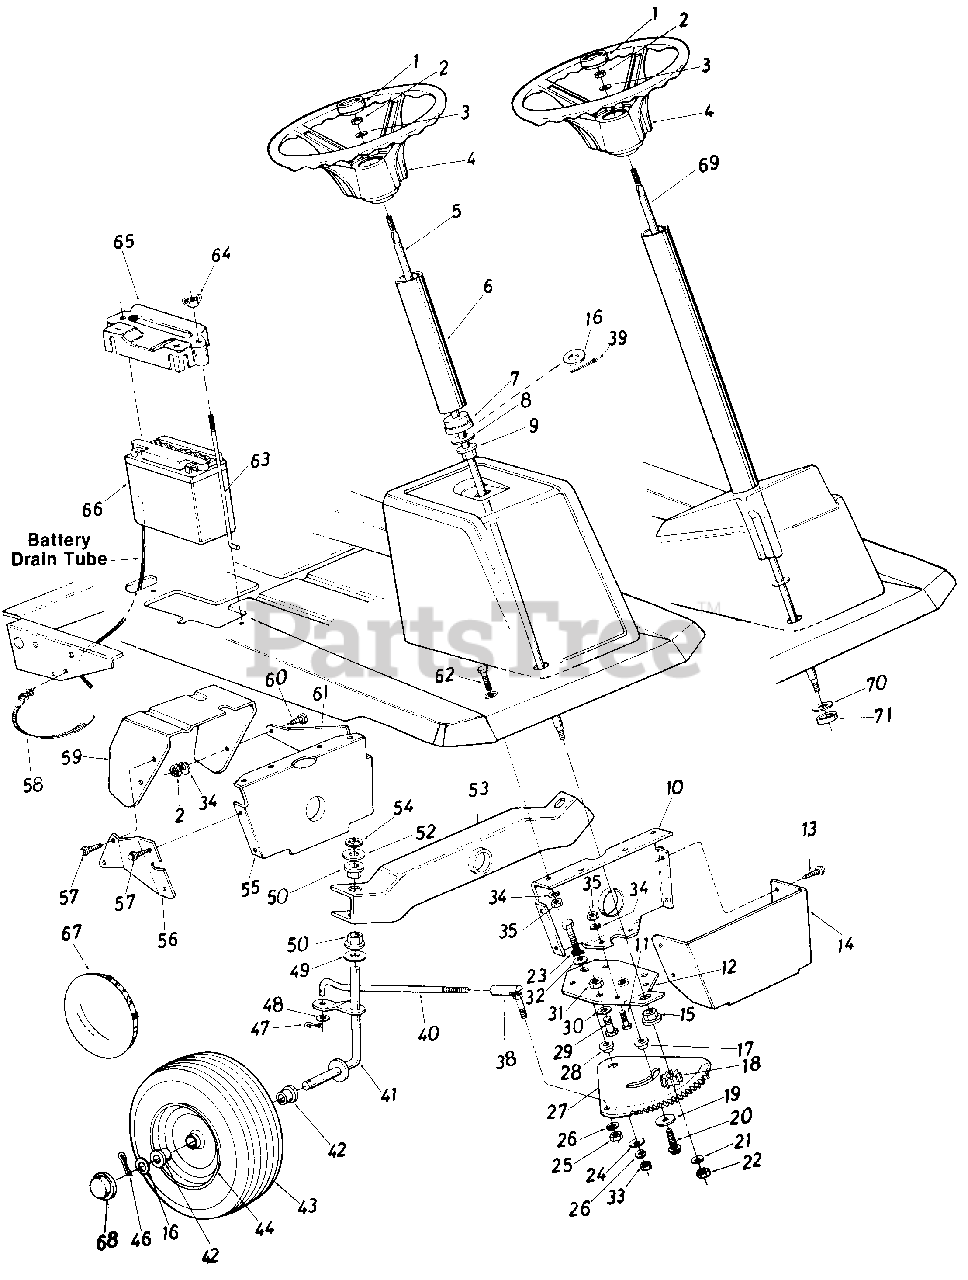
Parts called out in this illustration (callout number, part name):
1	Steering Wheel Cap
2	Hex Nut 5/16-18 Thd.
3	Bell-Wash. .345" I.D. x .88" O.D.
4	Steering Wheel Ass'y.
5	Steering Shaft
8	Fl-Wash. .640" I.D. x 1.25" O.D.
9	Hex Flange Bearing
10	Pivot Bar Bracket
11	Hex Bolt 5/16-18 x .75" Lg.
12	Steeri ng Gear Support Brkt.
13	Hex Wash. Hd. AB-Tap Scr. 1/4 x.62" Lg.
16	Fl-Wash. .640" I.D. x 1.62" O.D.
17	Shoulder Spacer .622 Dia. x .218
18	Steering Pinion Gear
19	Fl-Wash. .385" I.D. x 1.38" O.D.
20	Hex Wash. Hd. Self-Tap Scr. 3/8-16 x 1.25" Lg.
21	Fl-Wash. .34" I.D. x .68" O.D.
22	Hex Nut 5/16-24 Thd.
23	Hex Bolt 3/8-24 x 1.25" Lg. (Grade 5)
24	Fl-Wash. .385" I.D. x 1.38" O.D.
25	Hex Nut 3/8-24 Thd.*
26	L-Wash. 3/8" I.D.
27	Steering Gear Segment
28	Shoulder Spacer .622" Dia. x .218
29	Hex Bolt (Nylon) 1/2-13 x .75" Lg.
30	Fl-Wash. .530" I.D. x .930" O.D.
31	Hex Nut 1/2-13 Thd.
32	Bell-Wash. .385" I.D. x .88"
33	Hex Nut 3/8-24 Thd.
34	L-Wash. 5/16" I.D.
35	Hex Nut 5/16-18 Thd.
38	Bal I J oi nt Ass'y. 3/8-24 Thd.
39	Cotter Pin 1/8" Dia. x 1.00" Lg.
40	Steering Tie Rod
41	Front Axle Ass'y.-R.H.
42	Flange Bearing .632" I.D.
43	Front Wheel Ass'y. Comp.
44	Front Wheel Rim Only
46	Cotter Pin 1/8" Dia. x 1.25" Lg.*
47	Cotter Pin 1/8" Dia. x 1.00" Lg.*
48	Fl-Wash. .385" I.D. x .87" O.D.
49	Fl-Wash. .635" I.D. x 1.12" O.D.
50	Hex Flange Bearing
52	Fl-Wash. .635" I.D. x 1.12" O.D.
53	Pivot Bar Ass'y.
54	Speed Nut 5/8" I.D.
55	Pivot Bar Bracket
56	Bracket Reinforcement-R.H.
57	Hex Wash. Hd. AB-Tap Scr. 1/4 x.62" Lg.
58	Cable Tie
59	Clutch-Brake Pedal Ass'y.
60	Hex Bolt 5/16-18 x .75" Lg.
61	Bracket Reinforcement-L.H.
62	Hex Bolt 5/16-18 x .75" Lg.
63	Battery Hold Down Rod
64	Wing Nut Solid 1/4-20 Thd.
65	Battery Hold Down Cover
66	12V Battery
67	Chrome Hub Cap
68	Plastic Hub Cap
69	Steering Shaft Assy.
70	Fl-Wash. .62" I.D. x 1.50" O.D.
71	Spacer (Plastic)
